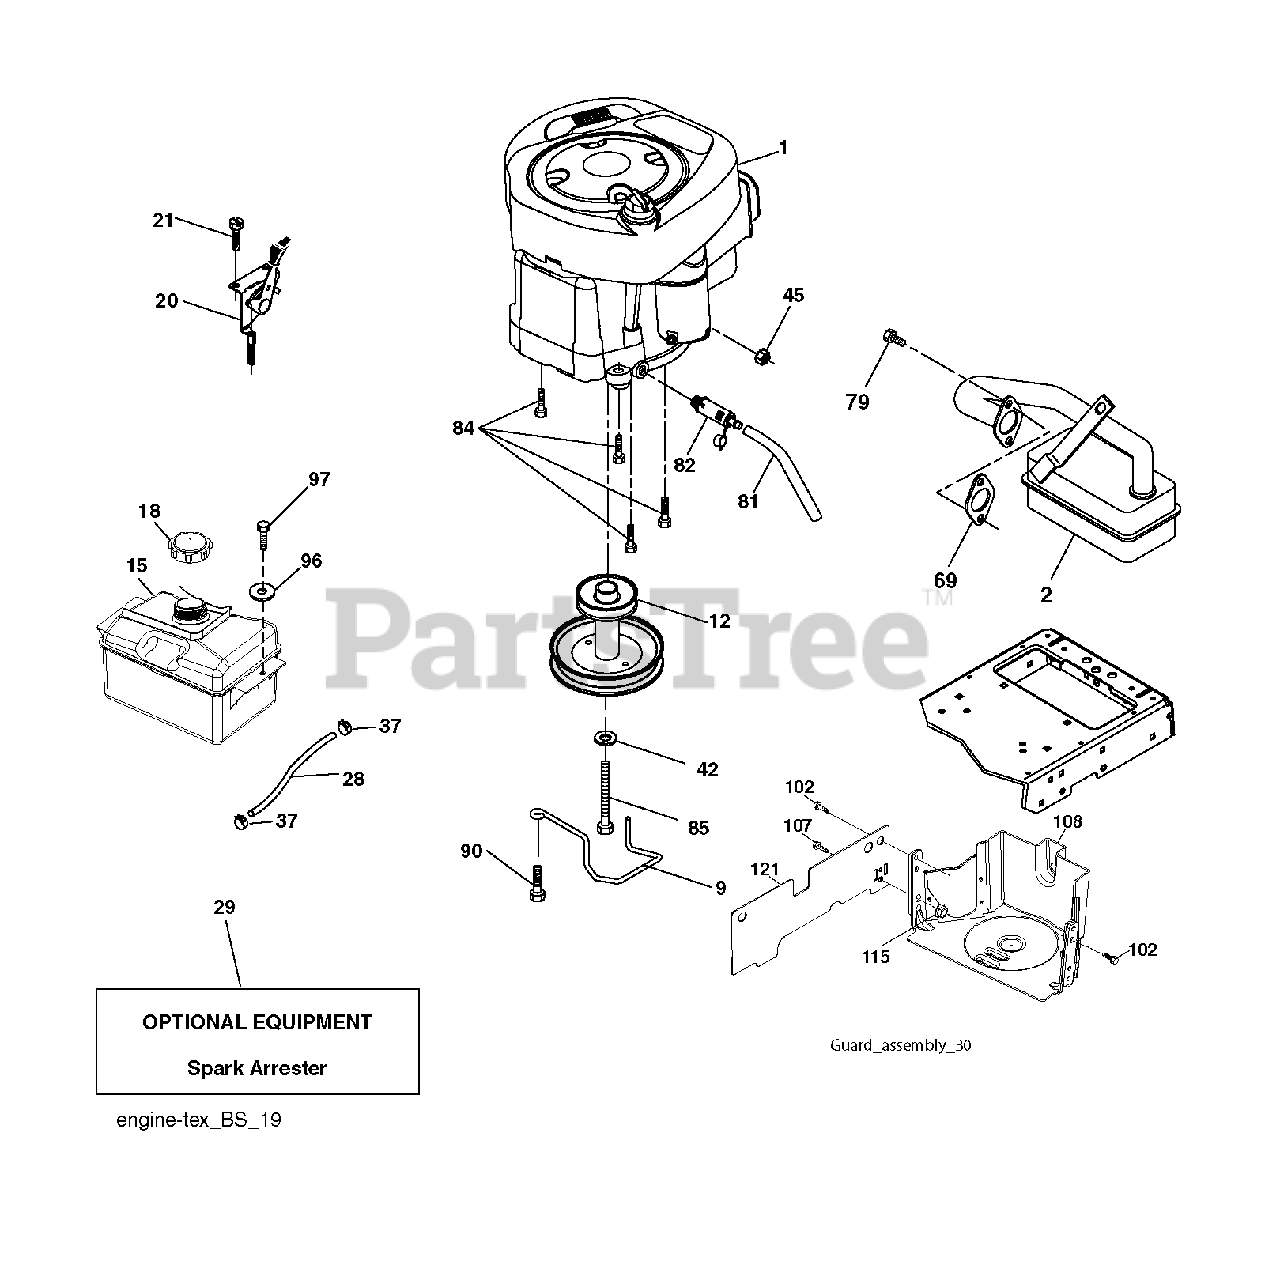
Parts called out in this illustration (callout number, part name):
9	KEEPER.BELT.ENGINE.3.25
12	PULLEY ENGINE
15	TANK FUEL FRT 1.5 GAL
18	FUEL CAP
20	CONTROL.TH/CK.C.
21	SCREW.#10 X 0.750.BOS THREAD
28	LINE.FUEL.20
29	ARRESTER SPARK (OPTIONAL)
37	HOSE CLAMP
42	LOCKWASHER
45	NUT
69	REPL BY 532 27 22-93
79	SCREW.SOCKET HD.5/16-1
81	TUBE, DRAIN OIL ASM.
82	PLUG DRAIN OIL EASY
84	SCREW.3/8-16
85	BOLT HEX 7/16-20X4-1/4"
90	SCREW 3/8-16X1
97	SCREW HEXWSHR 1/4-20X3/4
102	SCREW
107	SCREW.1/4-20X5/8
115	PALNUT 1/4
